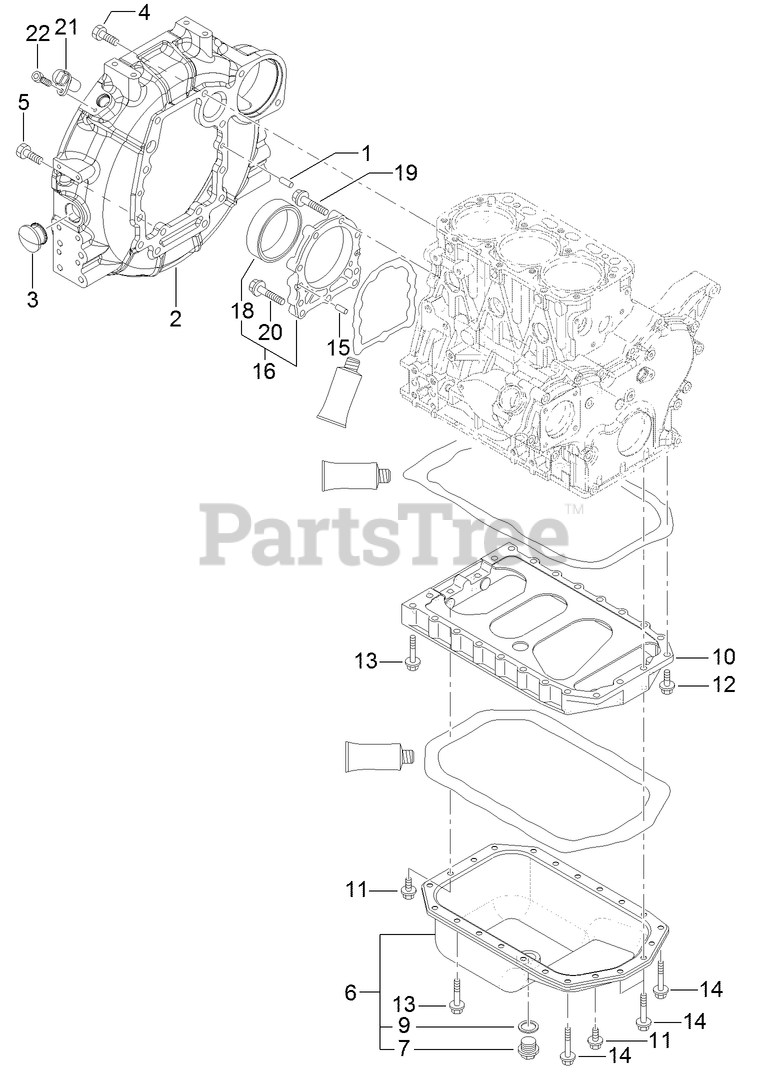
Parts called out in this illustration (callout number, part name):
2	HOUSING-FLYWHEEL
6	OIL PAN ASM
7	PLUG-DRAIN
9	WASHER-SEAL
10	SPACER
11	BOLT
16	CASE ASM
18	SEAL-OIL
21	SENSOR-REV, FLYWHEEL
